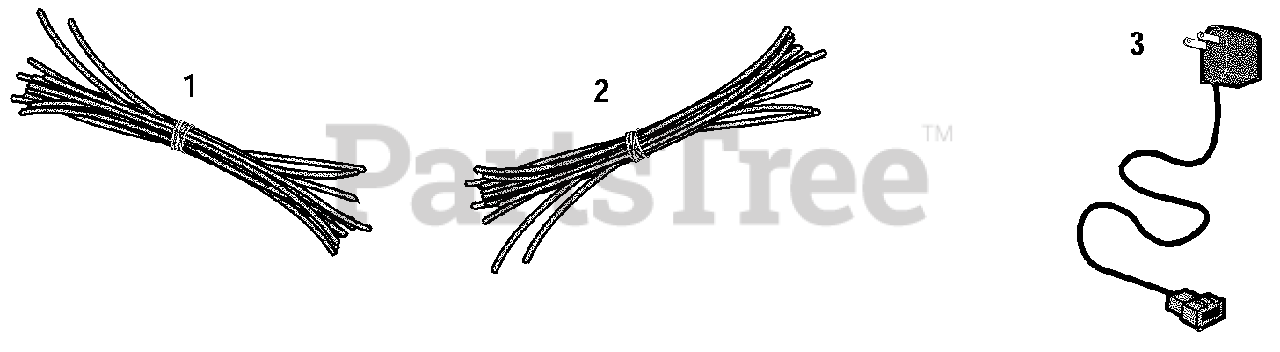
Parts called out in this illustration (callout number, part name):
1	Trimmer String Kit, .155"
2	Trimmer String Kit, .130"
3	Battery Charger
